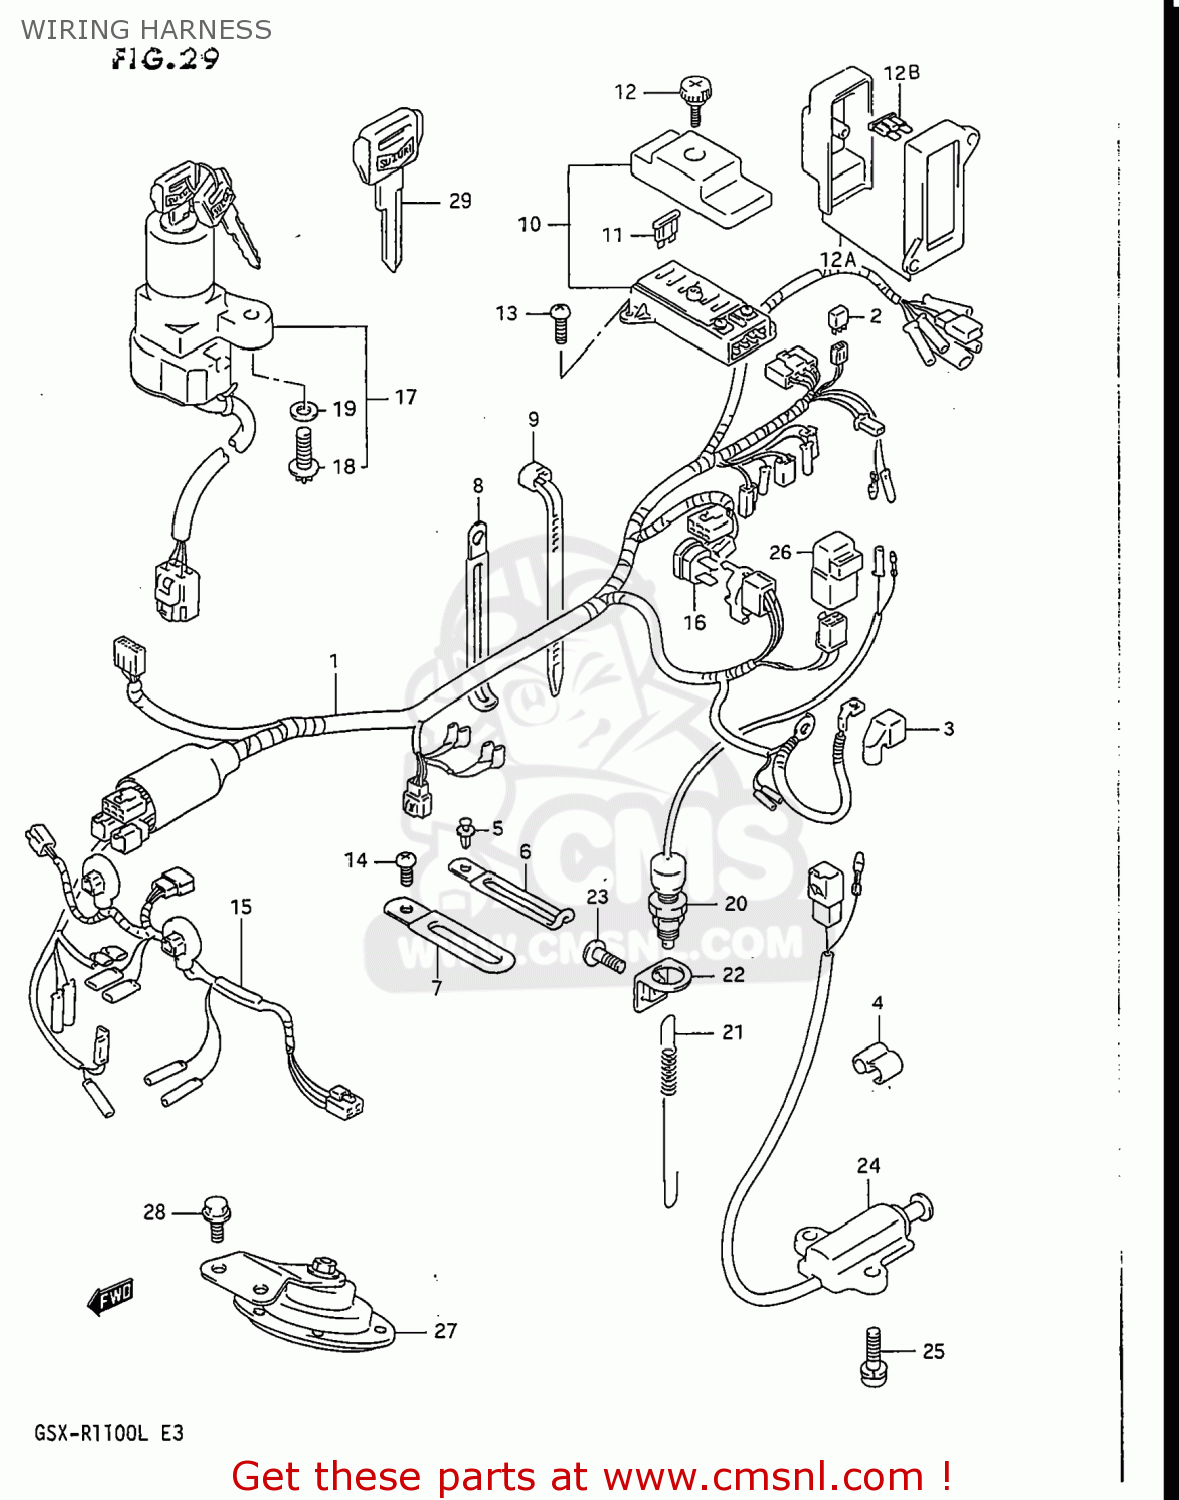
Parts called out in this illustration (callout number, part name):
1	HARNESS,WIRING
2	DIODE(STANLEY DE8804)
3	CAP,BATTERY PLUS
4	CLIP
5	CLIP
6	CLAMP
7	CLAMP
8	CLAMP
9	CLAMP(L:125)
10	BOX ASSEMBLY,FUSE
11	FUSE(10A)
12	SCREW,FUSE BOX
12A	BOX ASSY,FUSE
12B	FUSE(10A)
13	SCREW
14	SCREW
15	WIRE,HEADLAMP LEAD
16	BREAKER ASSY,CIRCUT
17	LOCK ASSEMBLY,STEERING
18	SCREW(6X18)
19	WASHER
20	SWITCH ASSY,STOP LAMP
21	SPRING
22	BRACKET,STOP LAMP SWITCH
23	SCREW(6X12)
24	SWITCH ASSEMBLY,SIDE STAND
25	SCREW
26	RELAY ASSEMBLY
27	HORN ASSEMBLY
28	BOLT
29	KEY,BLANK
